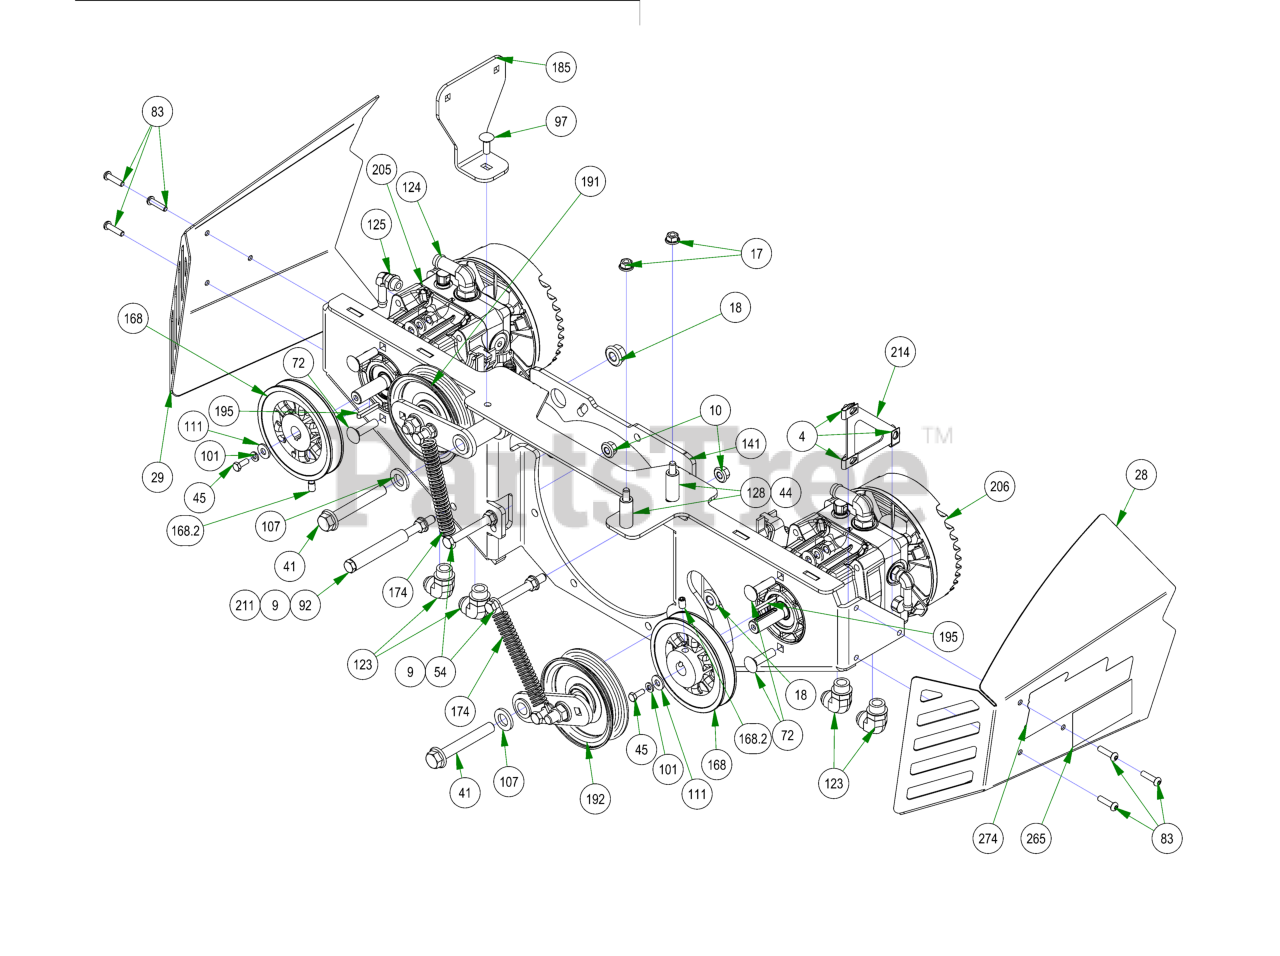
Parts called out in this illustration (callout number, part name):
4	1/4-20 Cage Nut
9	3/8-16 HEX SERRATED FLANGE NUT HARD/ZINC
10	3/8-16 NYLON INSERT FLANGE LOCKNUT (GR.F) ZINC
12	3/8-16 HEX NUT ZINC
17	5/16-18 NYLON INSERT FLANGE LOCKNUT ZINC
18	1/2-13 NYLON INSERT FLANGE LOCKNUT ZINC
21	5/16-18 HEX SERRATED FLANGE NUT HARD/ZINC
28	2019 Horizontal Pump Cover - Right - Black
29	2019 Horizontal Pump Cover - Left - Black
41	1/2-13 X 90MM HEX FLANGE BOLT W/SHOULDER (GR.8) ZINC
44	5/16-18 X 2-1/4 HEX CAP SCREW (GR.5) ZINC
45	M6-1.0 X 16MM DIN 933 HEX TAP BOLT (CL 8.8) ZINC
54	3/8-16 X 3-1/2 HEX CAP SCREW (GR.5) ZINC
72	3/8-16 X 1-1/2 CARRIAGE BOLT ZINC
83	1/4-20 x 1" BS C/S 18-8 SS
92	3/8-16 X 5-1/2 HEX CAP SCREW (GR.5) ZINC
97	5/16-18 X 7/8 CARRIAGE BOLT ZINC
101	1/4 SPLIT LOCKWASHER ZINC
104	3/8 SPLIT LOCKWASHER ZINC
107	.635 ID X 1.120 OD X .140 THICK FLAT WASHER NYLON
111	1/4 USS FLAT WASHER (3/4 OD) ZINC
113	5/16 USS FLAT WASHER (7/8 OD) ZINC
123	2019 Outlaw 90 Degree Pump Fitting #6801-10-08
124	90 Degree Fitting, 1/2 x 3/4, 4601-8-8
125	90 Degree Fitting, 3/8 s 9/16
128	.380 ID X .625 OD X 1.500 LGTH 2019 OUTLAW BRAKE HANDLE SPACER ZINC
141	2020 Diesel Pump Plate Weldment - Painted
168	5" PUMP PULLEY W/ SET SCREW
168.2	5/16-24 X 1/2 SOCKET SET SCREW KNURLED CUP POINT
174	ZT and ACS Handle Spring
185	2019 Diesel Muffler Bracket
191	2020 Diesel Pump Tensioner Assembly LH
192	2020 Diesel Pump Tensioner Assembly RH
195	5MM X 36MM SQ MACHINERY KEY C1018 ROUNDED ENDS
205	2019 Rogue/Renegade Left Pump 16cc
206	2019 Outlaw Renegade Right Pump 16cc
211	3/8 hose 4" long
214	Pump Plate Clip Nut Holder
265	PERKINS Decal
274	2019 Renegade 1100cc Pump Decal
